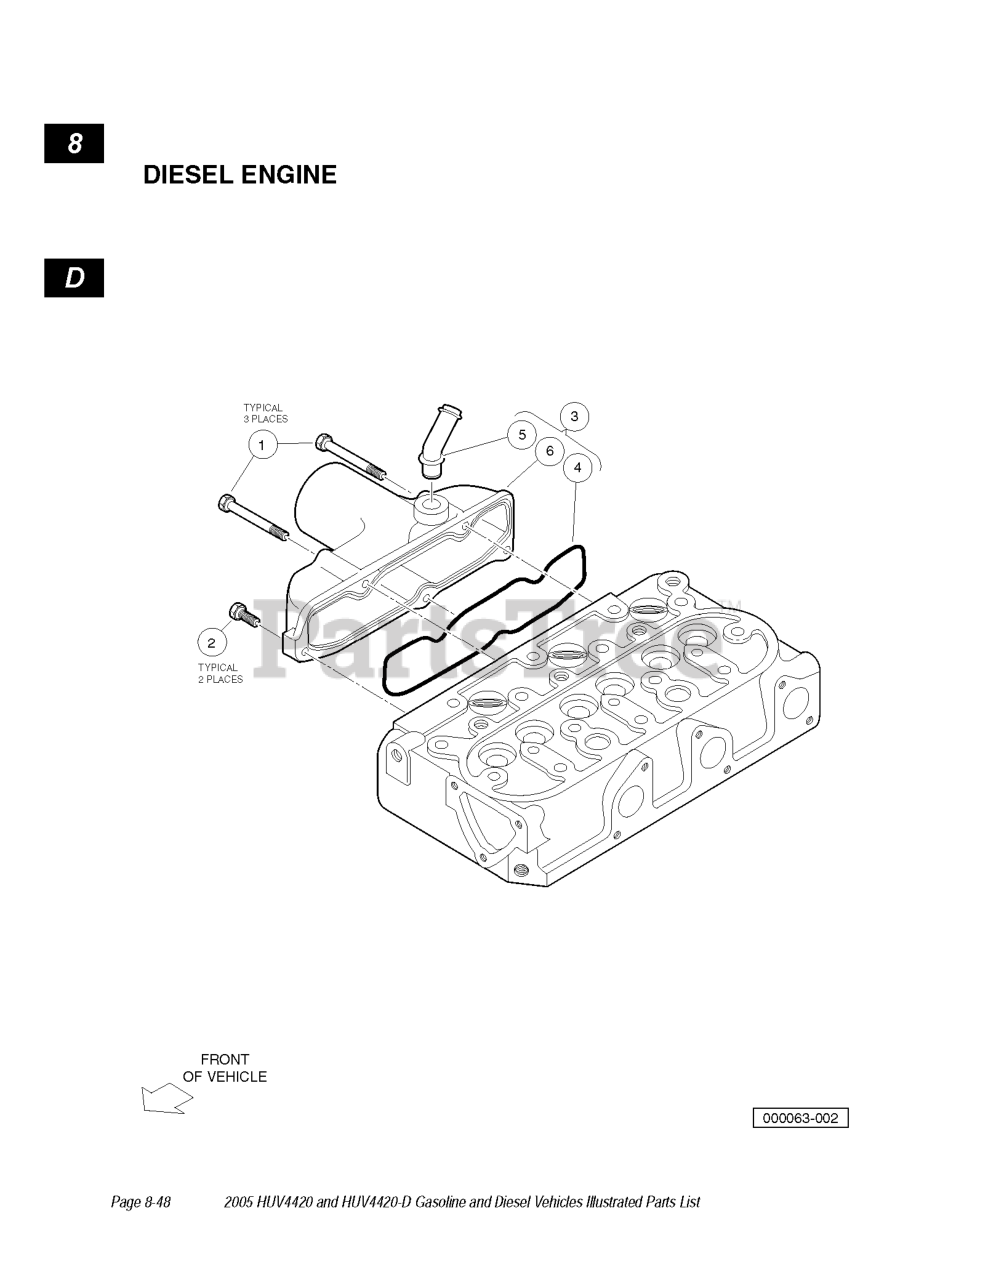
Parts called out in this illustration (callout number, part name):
1	BOLT, M6 X 1 X 45
2	BOLT, D722 INTAKE MANFLD LOWER
3	ASSY-INTAKE MANIFOLD
4	GASKET, IN-MANIFOLD
5	PIPE-BRATHR-INTAKE
